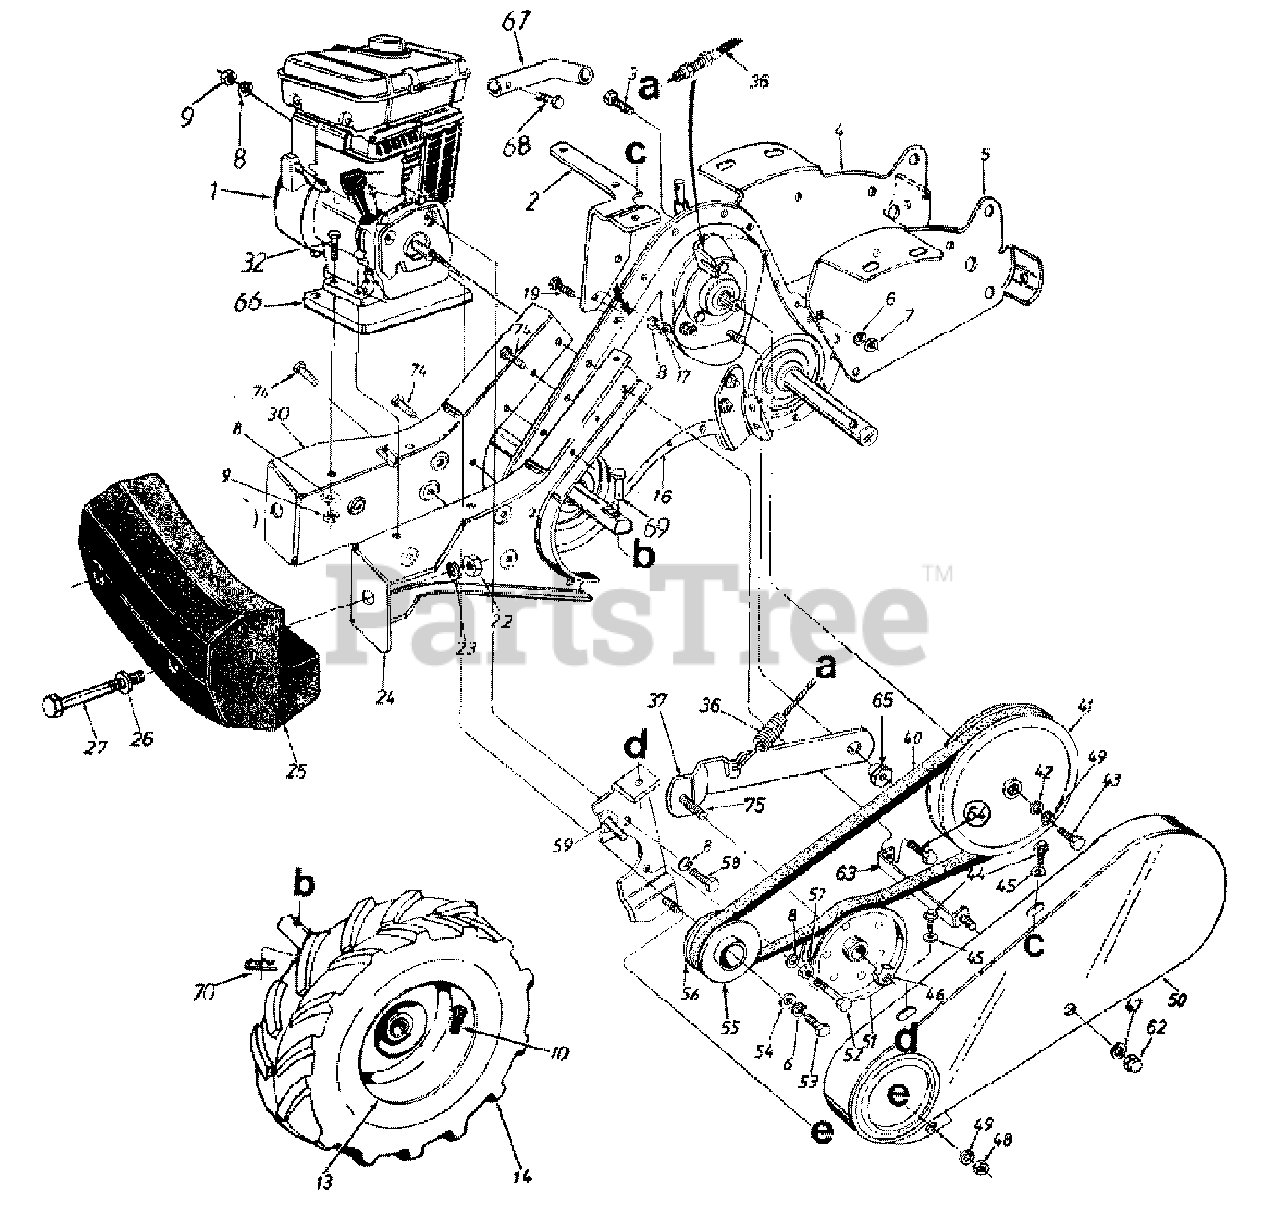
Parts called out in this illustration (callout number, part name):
1	Engine
4	Tine Shield Mtg. Brkt.-R.H.
7	Hex Nut 3/8-16 Thd.
8	L-Wash. 5/16" I.D.
9	Hex Nut 5/16-18" Thd.
10	Air Valve
16	Gear Case Ass'y. Comp.
17	Hex Nut 5/16-18 Thd.
19	Hex Bolt 5/16-18 x .75" Lg.
22	Hex Nut 1/2-13 Thd.
23	L-Wash. 1/2" I.D.
26	Fl-Wash. .510" I.D. x 1.0"
27	Hex Bolt 1/2-13 x 5.00" Lg.
32	Hex Bolt 5/16-18 x 2.75"
36	Clutch Control Cable 46" Lg.
37	Idler Bracket
40	V-Belt
41	Fl-Pulley 8" O.D.
42	Fl-Wash. 1/4" I.D. x .93" O.D.
43	Hex Bolt 1/4-28 x .75" Lg.
44	Hex Wash. Hd. S-Tap Scr. 1/4-20 x .50" Lg.
45	Fl-Wash. .281" I.D. x .625"
46	Cent. L-Jam Nut 3/8-16 Thd.
48	Hex Nut 1/4-20 Thd.
49	L-Wash. 1/4" I.D.
51	Fl-Idler w/Flanges 3.75" O.D.
52	Hex Bolt 5/16-24 x 1.75"
53	Hex Bolt 3/8-24 x 1.00" Lg.
55	Outer Engine Pulley Half
56	Inner Engine Pulley Half
57	Hex Nut 5/16-24 Thd.
58	Hex Bolt 5/16-24 x .62" Lg.
59	Belt Keeper Ass'y.
62	Hex Cap Nut 1/4-28 Thd.
63	Belt Cover Brkt. Ass'y.
64	Hex Bolt 5/16-18 x 1" Lg. (Gr. 5)
65	Shld. Nut
66	Engine Spacer Block
67	Outlet Pipe
68	Hex Wash. Hd. AB-Tap Scr. #8 x .5" Lg.
69	Clevis Pin
70	Hairpin Clip
74	Screw 5/16-18 x 1"
75	Hex Hd. Cap Scr. 3/8-16:1.25" Lg.
